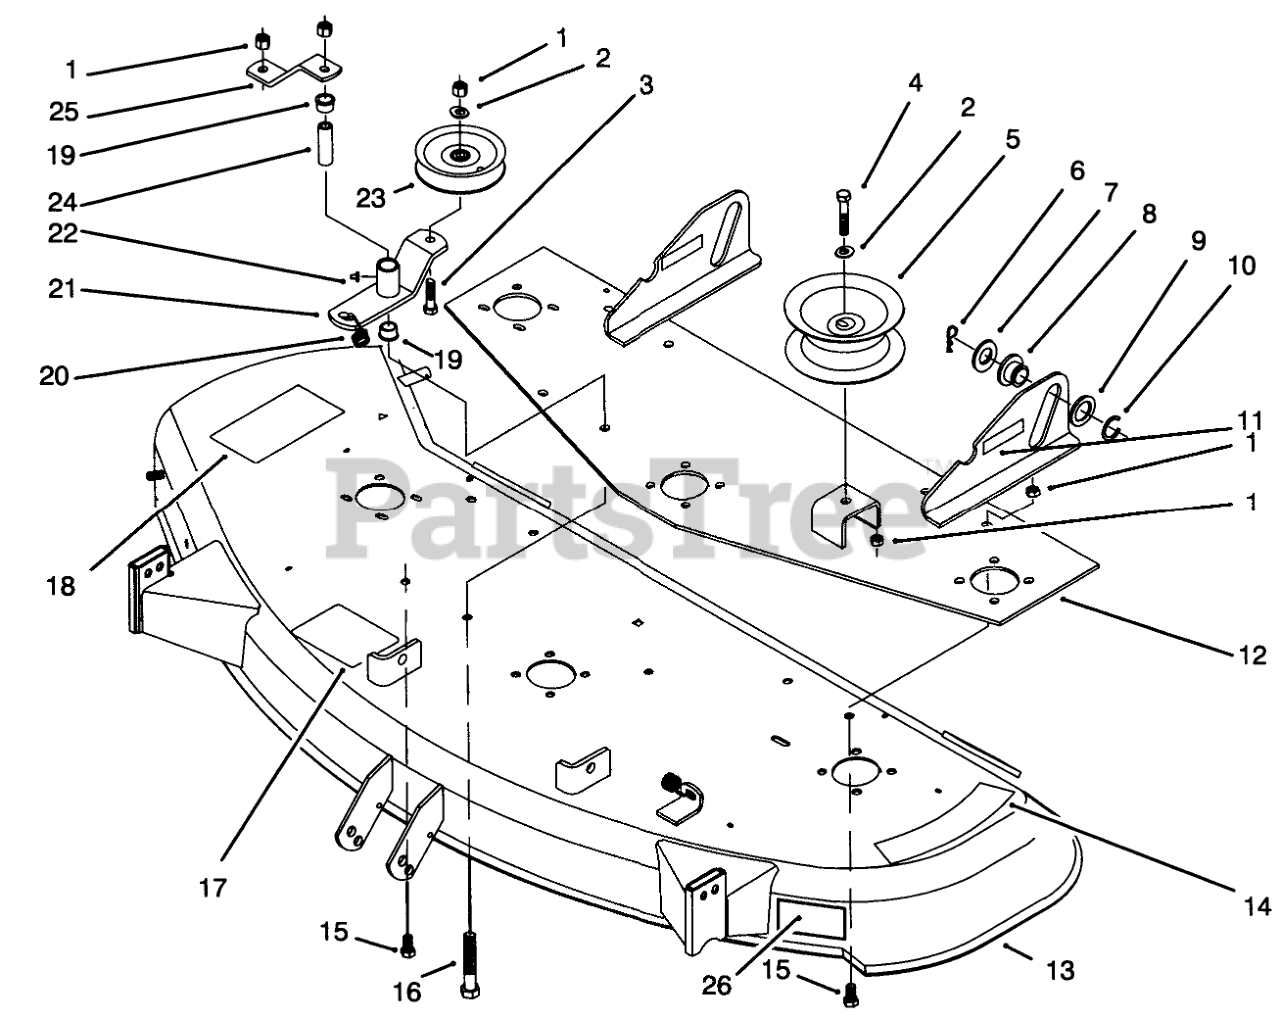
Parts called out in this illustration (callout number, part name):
1	NUT-LOCK, NI
2	WASHER-FLAT
3	SCREW-HH
4	SCREW-HH
5	Pulley-Idler
6	Pin-Cotter
7	WASHER-FLAT
8	ROLLER-LIFT
9	Washer
10	RING-RETAINING
11	Decal-Attach-A-Matic
12	Plate-Support
13	Deck & Decal Assy. (Incl. ref. #14 & 18)
14	DECAL - DANGER
15	SCREW-HH
16	SCREW-HH
17	DECAL-BELT INSTALL
18	DECAL-DANGER, THROWN OBJECT
19	BUSHING
20	SPRING - EXTENSION
21	Arm-Idler
22	FITTING-GREASE
23	Pulley-Idler
24	SPACER
25	Strap-Brace
26	DECAL - WHEEL ADJUSTMENT
